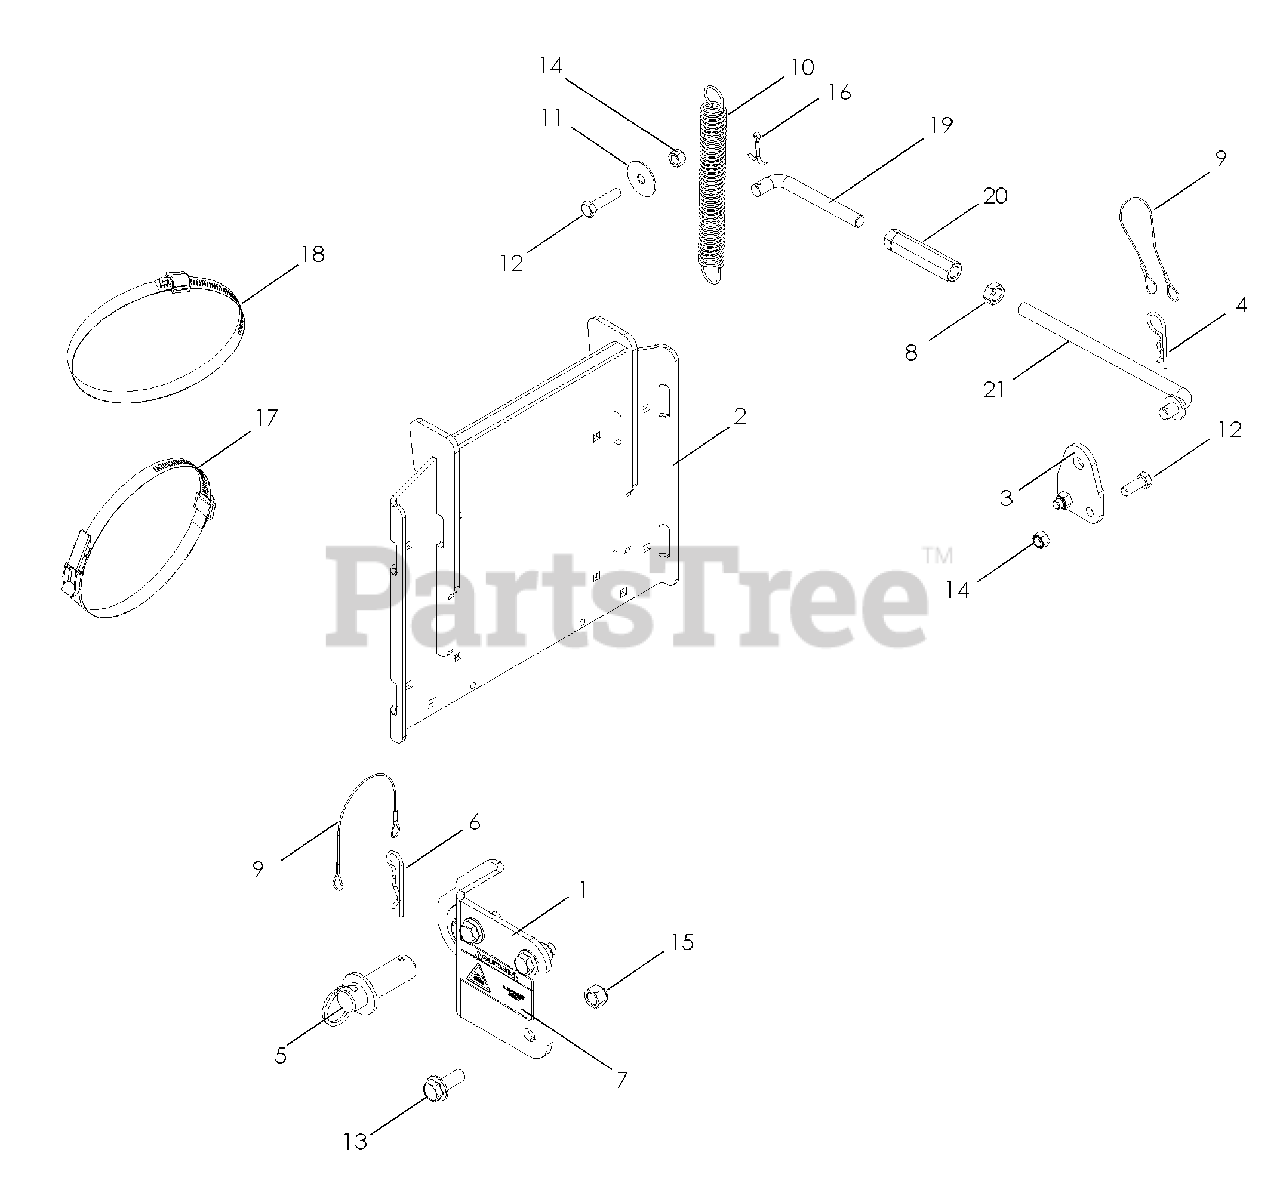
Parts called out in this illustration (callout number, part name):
1	BRACKET, RT W/DECAL
1	BRACKET, LT
2	REAR GUARD
3	SUPPORT BRACKET
5	PIN, HITCH
7	DECAL, HOT SURFACE
8	NUT 1/2-20 HEX JAM
11	WASHER, FRICTION
12	HCS 3/8-16 x 1
13	HFCS 1/2-13 x 1 1/4 WHIZLK
14	NUT 3/8-16 HEX NYLOC
15	NUT 1/2-13 HEX NYLOC
16	PIN, COTTER 5/32 x 1 1/4
17	OVER CENTER BAND
18	HOSE CLAMP
19	SUPPORT LINKAGE, LH
20	TURNBUCKLE 1/2
21	SUPPORT LINKAGE
